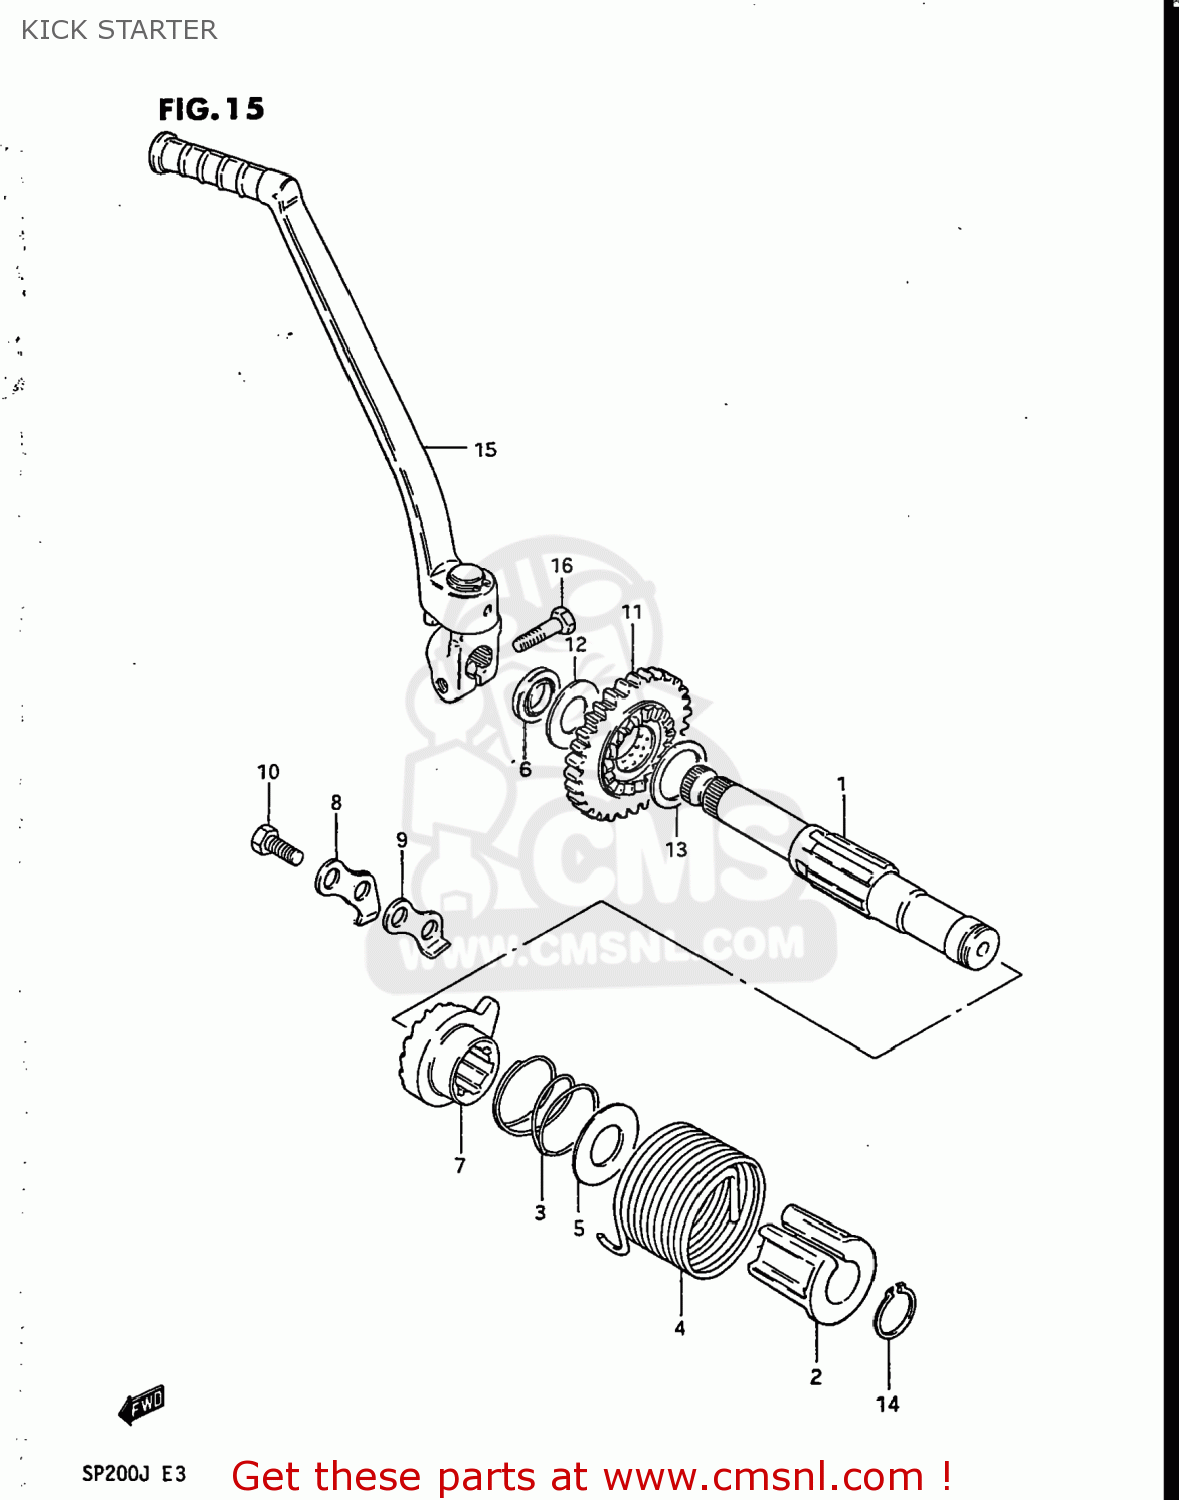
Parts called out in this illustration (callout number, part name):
1	SHAFT,KICK STARTER
2	GUIDE,KICK STARTER SFT SPRING
3	SPRING
4	SPRING
5	WASHER
6	SEAL,OIL(16X24X5)
7	STARTER,KICK
8	GUIDE,KICK STARTER
9	STOPPER,KICK STARTER
10	BOLT
11	GEAR,KICK STARTER DRIVE
12	WASHER(16X30X1)
13	WASHER
14	CIRCLIP
15	LEVER ASSY,KICK STARTER
16	BOLT 8X25
